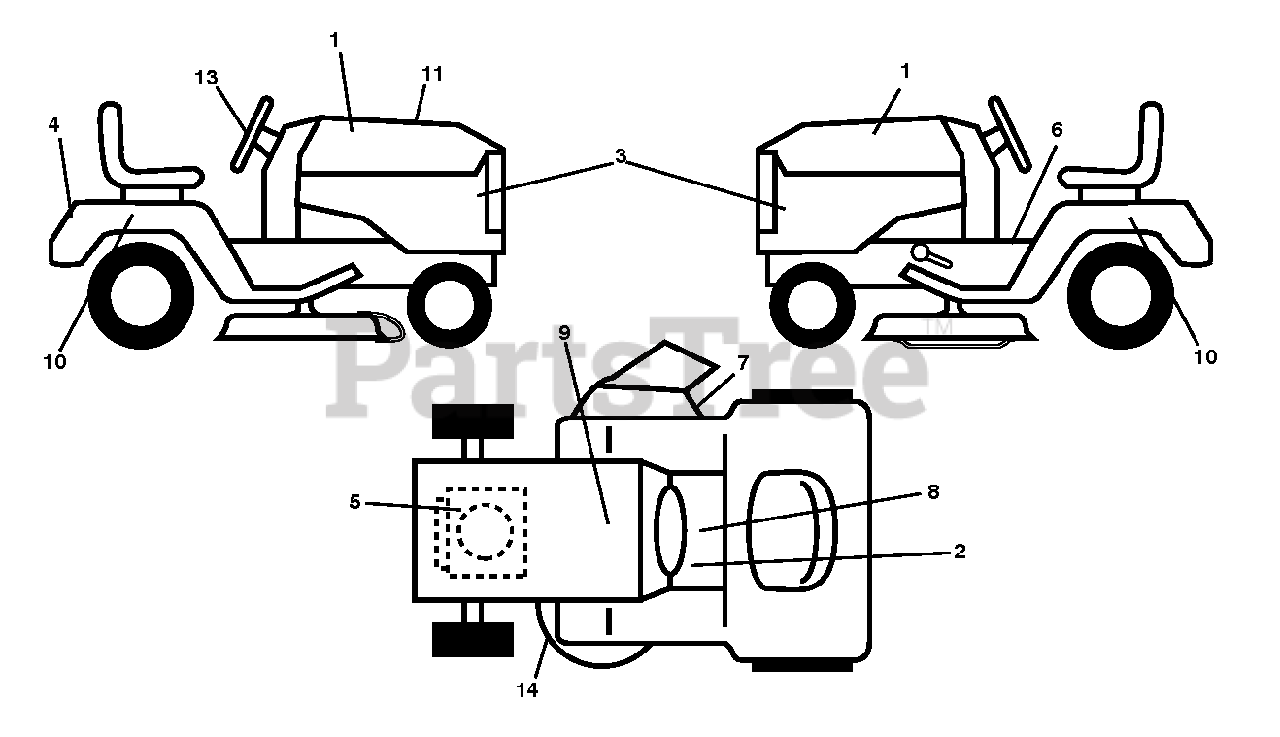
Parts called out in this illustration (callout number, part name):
2	DECAL, WARNING SPARK ARRESTOR
5	DECAL.ENG.BS.22.XRD.TWN.278445
6	Fender Warning Decal, English
7	DECAL.WARN.KEEP.HAND.AWAY
9	DECAL BTRY SYMBOLS
13	DECAL.STEER.WHEEL.POULAN.PRO
14	DECAL V BELT SCHEMATIC
